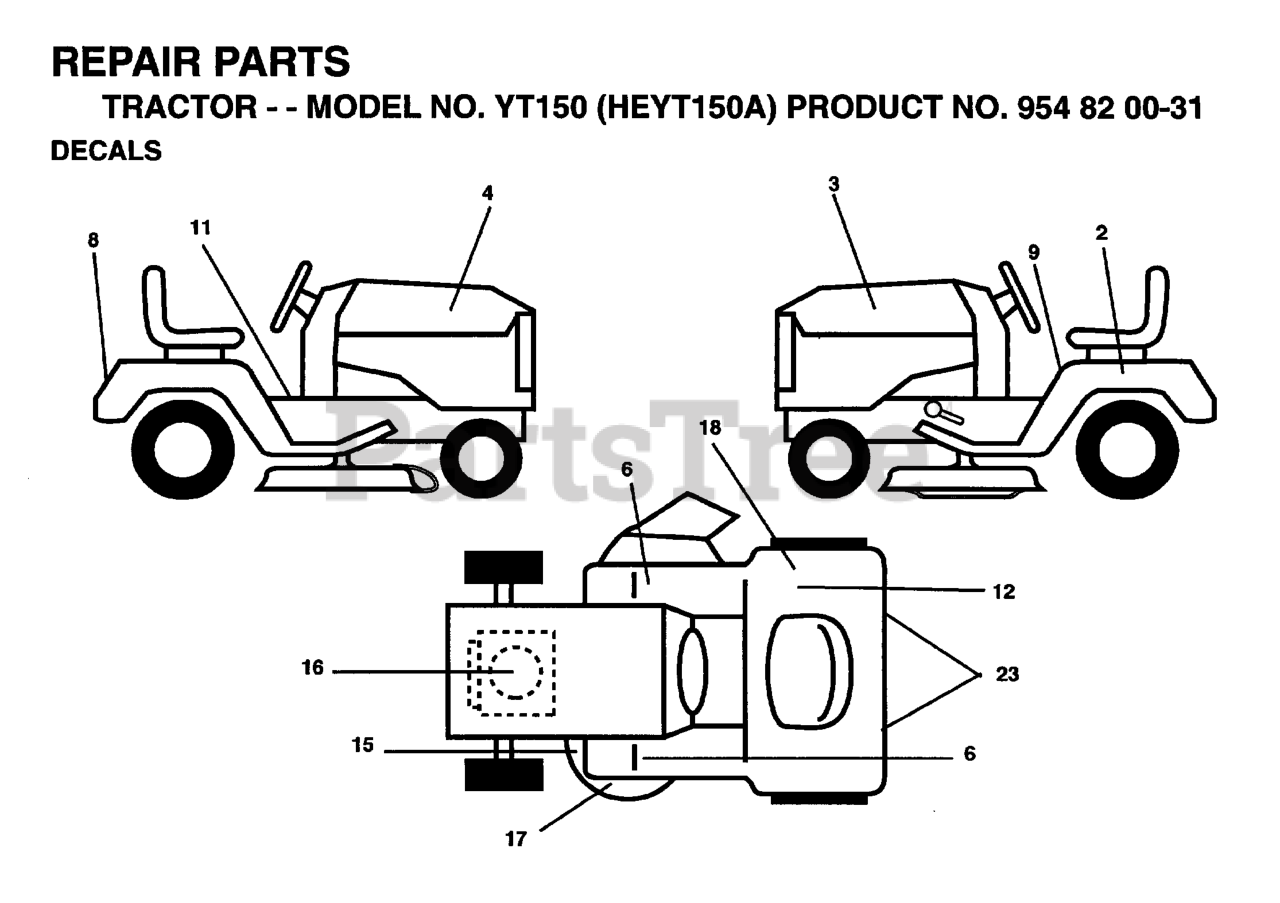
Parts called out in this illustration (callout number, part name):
2	DECAL, BATTERY DANGER
3	Decal Hood LH
4	Decal Hood RH
6	PAD FOOTREST
8	DECAL FENDER HUSQ
9	DECAL READ OWNER'S MAN SYMS
11	DECAL PARK BRAKE
15	DECAL V-BELT SCHEMATIC
17	DECAL MOWER CUT/FINGER
18	DECAL EUROPE STANDARD CE
23	REFLECTOR-TAIL YT
